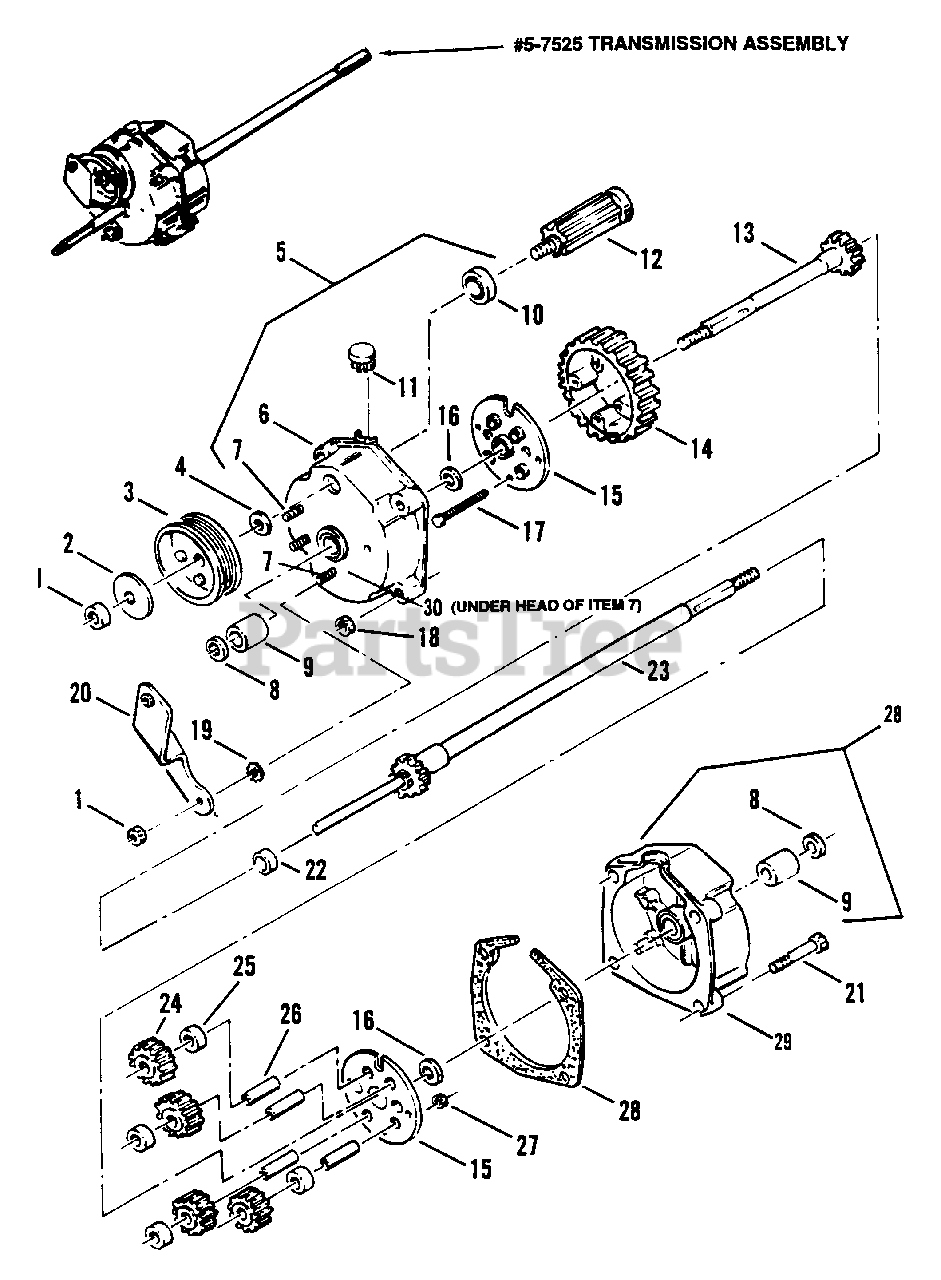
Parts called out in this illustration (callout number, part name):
1	NUT, 5/16-24 Hex Lock
2	WASHER, Spring
3	PULLEY, Poly-Vee Belt
4	WASHER, Spring
5	ASSEMBLY, Housing Right
5-7525	ASSEMBLY, Transmission
6	HOUSING, Right Side
7	SCREW, 5/16-24 x 1-1/8" Rib Neck
8	SEAL, 5/8 I.D.
9	BEARING, Differential
10	BEARING, Ball
11	PLUG, Housing
12	GEAR, Input
13	AXLE, Short
14	GEAR, Differential (46 Tooth)
15	PLATE
16	WASHER, Thrust
17	SCREW, #10-32 x 1-1/2" Hex Head Cap
18	GASKET, Housing
19	WASHER, 5/16 Internal/External Tooth Lock
20	BRACKET, Differential
21	SCREW, 1/4-20 x 1-1/4" Self-Tapping
22	SPACER, Axle Gear
23	AXLE, Long
24	GEAR, Pinion (12 Tooth)
25	SPACER, Pinion Gear
26	SHAFT, Pinion
27	NUT, #10-32 Hex Lock
28	ASSEMBLY, Housing Left
29	HOUSING, Left Side
30	GASKET, 5/8 O.D.
